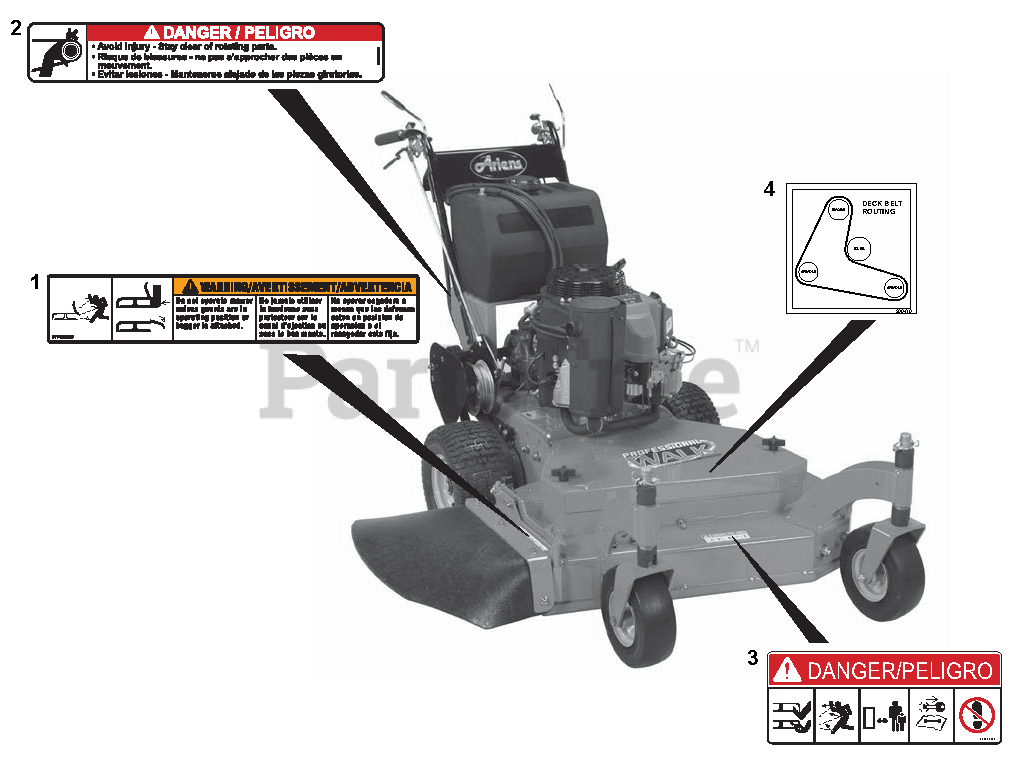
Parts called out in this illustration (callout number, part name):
1	DECAL, WARNING
2	DECAL-DANGER-BELT ROTATING
3	DECAL, MOWER PAN DANGER
4	DECAL, DECK BELT ROUTING
